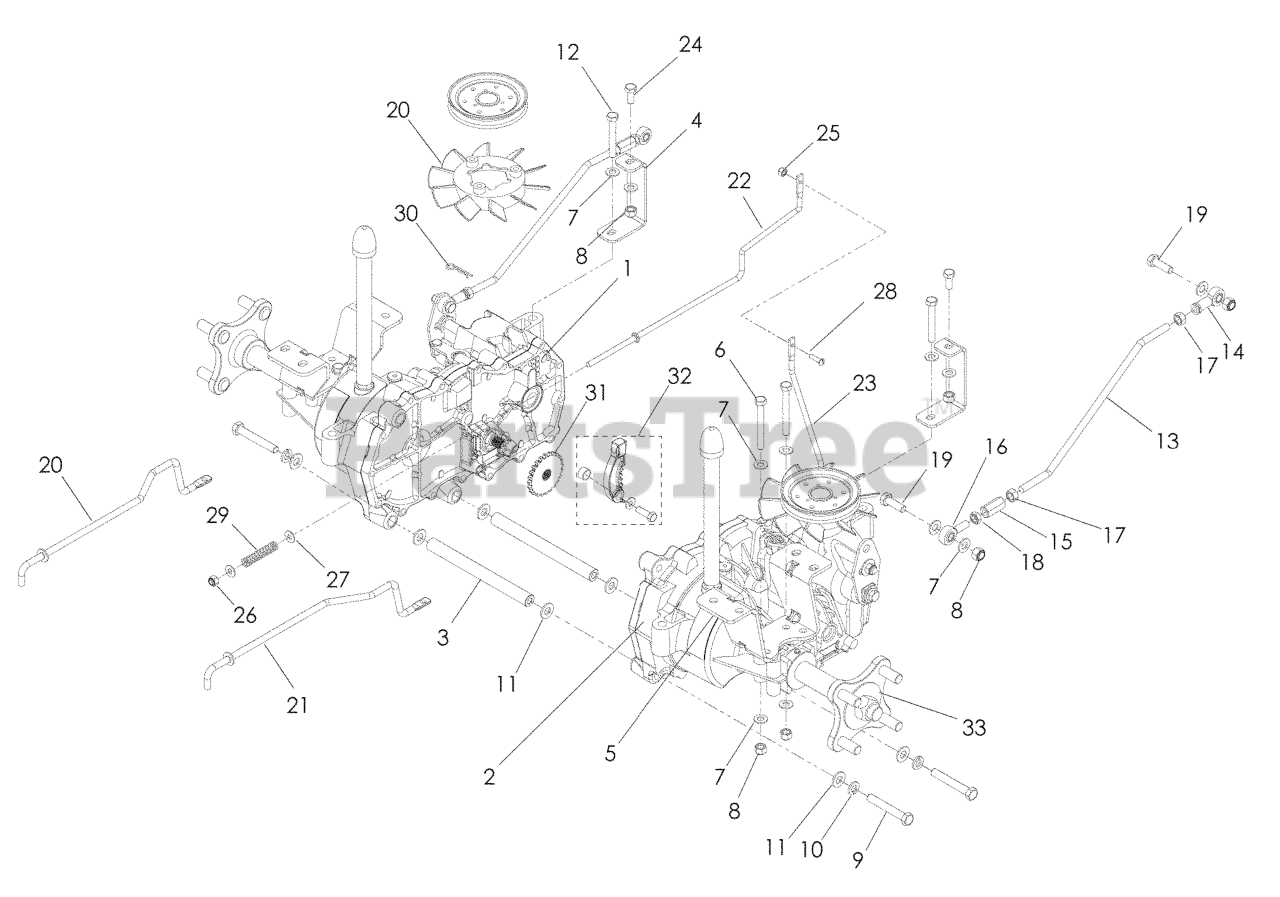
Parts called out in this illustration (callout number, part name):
1	HG_EZT, LT
2	HG_EZT, RT
3	SPACER TUBE, EZT
4	SUPPORT.FRONT.TRANS.BLACK.
5	EZT MOUNT, REAR, BLACK
6	HCS 5/16C X 2-3/4
7	FLAT WASHER 5/16 SAE
8	NUT 5/16 NYLOC
9	HCS 3/8C X 2 1/2
10	SLW 3/8 STD
11	WASHER 3/8 SAE FLAT
13	RP.ROD, MOTION CONTROL
14	RH ROD END
15	ROD END COUPLER
16	RP.ROD.END.LH
18	NUT 5/16F LEFTHAND
19	HCS 5/16C X 1
20	HG_HYDRO FAN 51365
21	LINKAGE, BYPASS, EZT
22	LINKAGE BRAKE LT
23	LINKAGE BRAKE RT
24	HCS 5/16C X 3/4
25	NUT 10-24 NYLOC
26	NUT.1/4-20.HEX.NYLOC.ZD
27	WASHER 1/4 SAE
28	SCR #10-24 X 3/4
30	HAIRPIN #2
31	HG_DISC COG BRAKE 51635
32	HG_KIT BRAKE ARM (EZT)
33	HUB KIT (H-G #70314)
